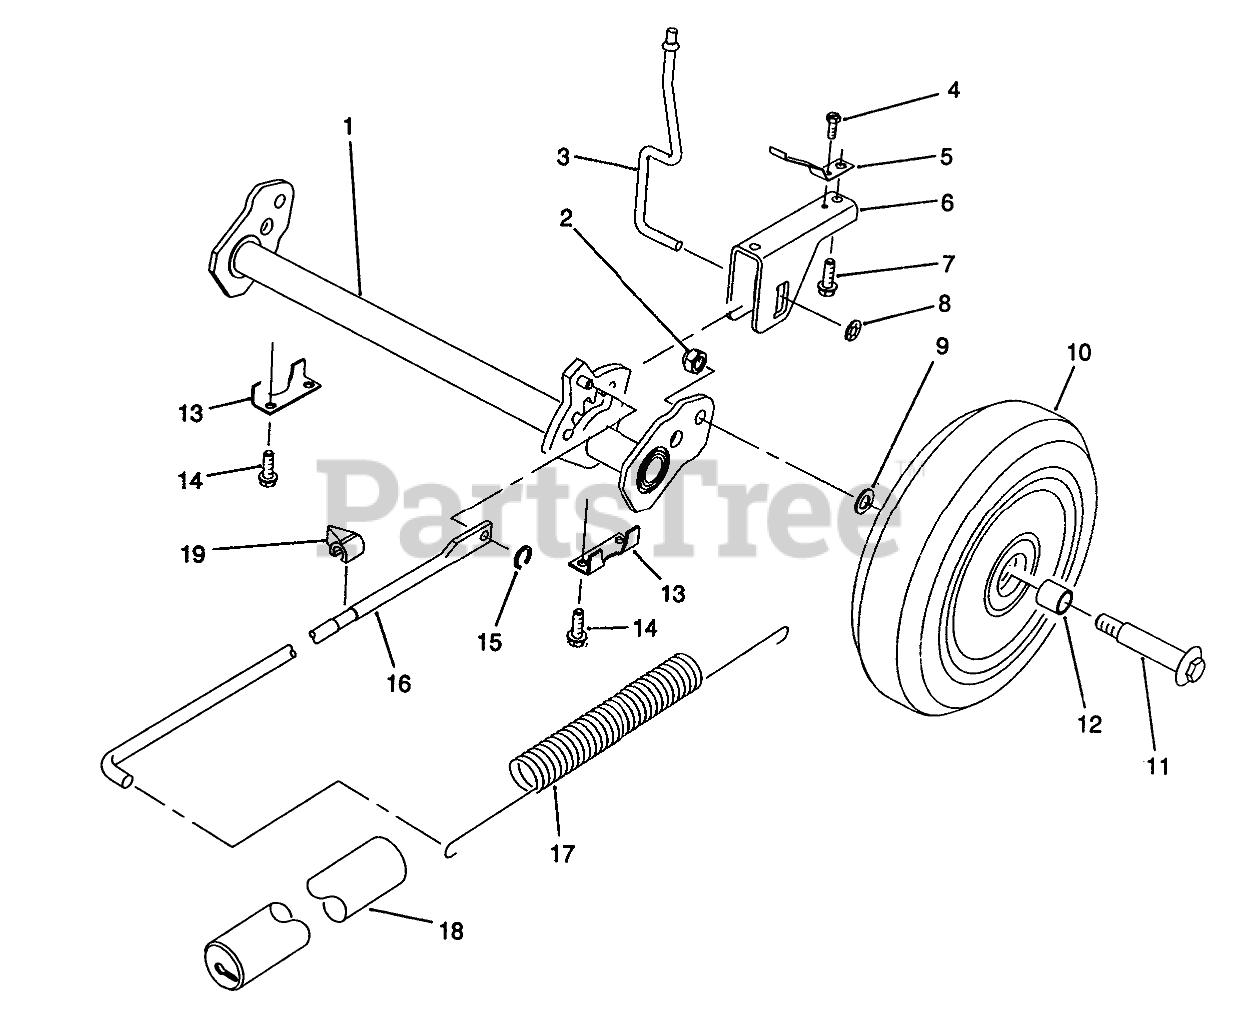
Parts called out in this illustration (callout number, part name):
1	PIVOT ARM REAR WA
2	NUT-HEX
3	TRIGGER ROD
4	SCREW 8 - 32 X 250
5	SPRING - TRIGGER RET
6	SADDLE - HOC
7	SCREW
8	PUSHNUT
9	WASHER
10	Wheel & Tire Assembly (Incl. Ref. #12)
11	BOLT-WHEEL
12	BUSHING
13	REAR SECURING PLATE
14	SCREW-HWH
15	GRIP RING
16	LINK ROD
17	SPRING-COUNTERBALANCE
18	COVER-SPRING
19	INDICATOR-HEIGHT OF CUT
